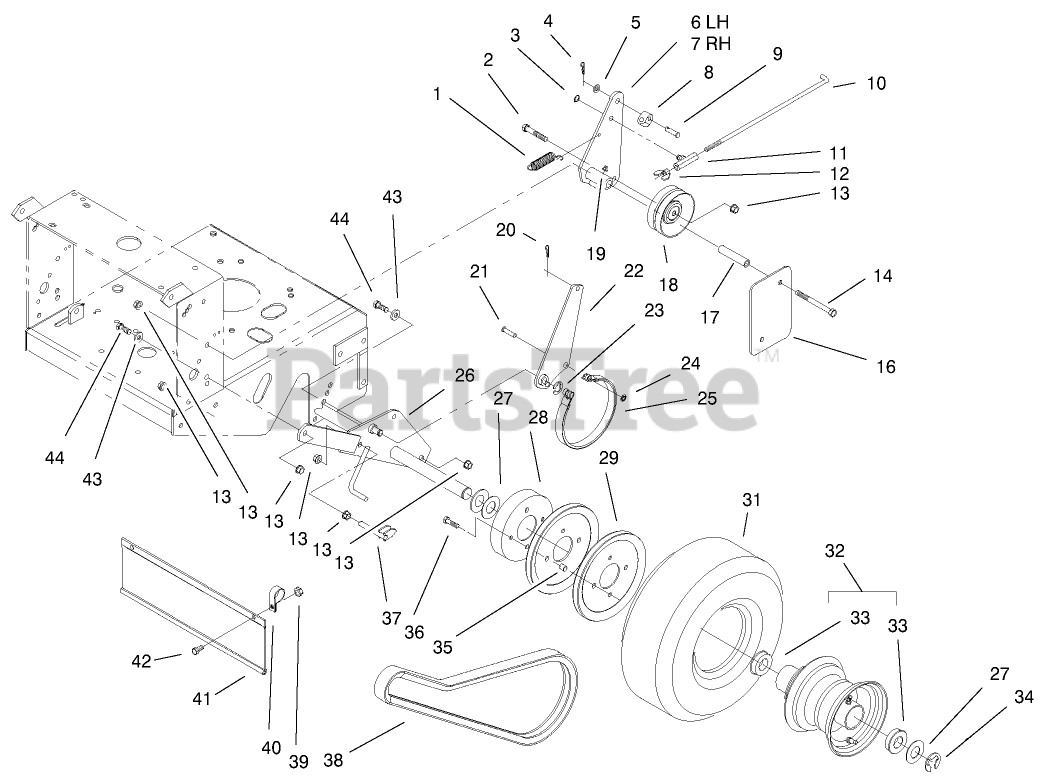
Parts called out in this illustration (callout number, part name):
1	Spring-Extension
2	SCREW-HH
3	Ring
4	PIN-COTTER
5	WASHER-PLAIN
6	Idler Arm ASM LH
7	Idler Arm ASM RH
8	FITTING-ROD
9	PIN-CLEVIS
10	Brake Rod
11	Swivel
12	Wingnut
13	NUT-HHF, WHIZ
14	SCREW-HH
16	Shield
17	Idler
18	Idler-Wheel Drive
19	FITTING-GREASE
20	PIN-COTTER
21	Pin
22	Brake Arm ASM
23	Ring-Snap
24	Nut
25	Band-Brake
26	Axle ASM
27	Spacer
27	Spacer-18 GA
28	Drum-Brake
29	Sheave
31	Tire
32	Rim Only w/Bearings
33	Bearing
34	Ring,Snap E
35	Spacer
36	Bolt-Whiz Lock
37	Scraper
38	Belt-Drive
39	NUT-LOCK, NI
40	CLAMP-R
41	Shield-Trailing
42	SCREW-HH
43	Washer
44	SCREW-HH
